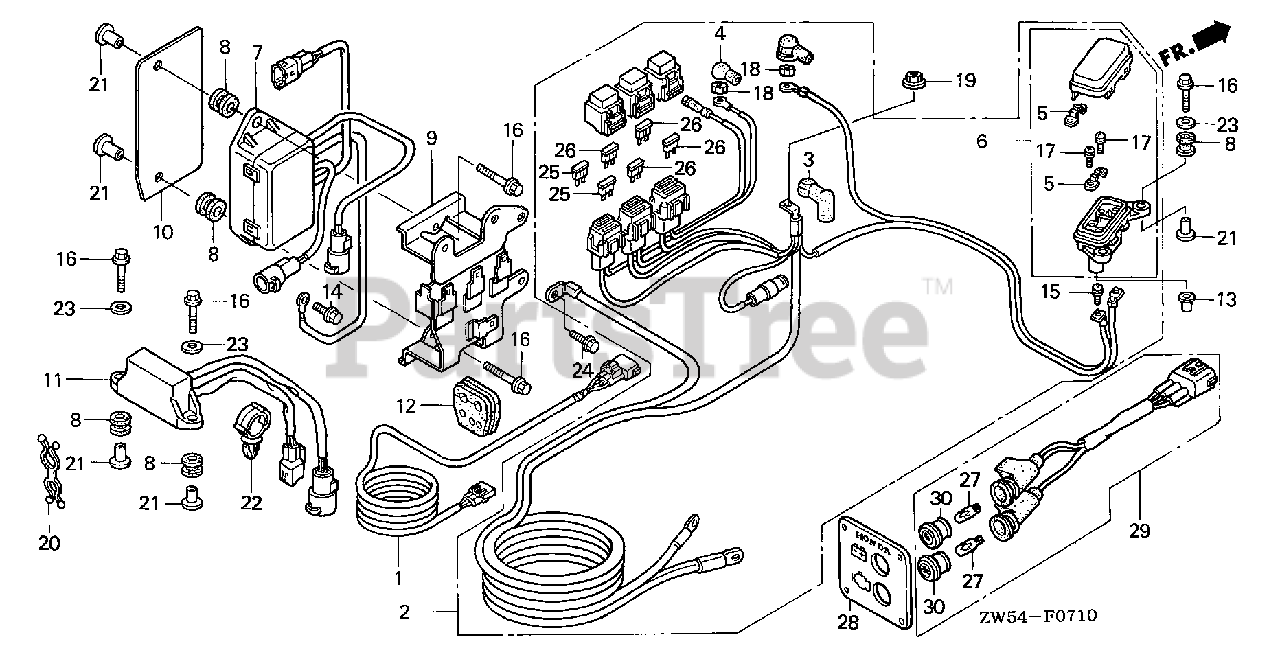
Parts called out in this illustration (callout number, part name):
1	WIRE ASSY., INDICATOR
2	CABLE ASSY., STARTER
3	COVER, STARTER TERMINAL
4	COVER A, MAGNETIC SWITCH
5	FUSE (90A)
6	BOX ASSY., FUSE (90A)
7	RELAY ASSY., POWER TILT
8	GROMMET, RELAY
9	BRACKET, RELAY
10	INSULATOR, RELAY
11	RELAY ASSY., MAIN
12	GROMMET, CASE (LOWER) (A)
13	GROMMET A, LEG SHIELD
14	BOLT, FLANGE (6X12)
15	BOLT-WASHER (5X9)
16	BOLT, FLANGE (6X25)
17	SCREW-WASHER (5X10)
18	NUT, HEX. (6MM)
19	NUT-WASHER (8MM)
20	CLIP, PURSE LOCK
21	COLLAR, MODULE IGNITION CONTROL CASE (CDI)
22	CLIP, WIRE HARNESS (BLACK)
23	WASHER, PLAIN (6MM)
24	BOLT, FLANGE (8X18)
25	FUSE, BLADE (10A)
26	FUSE, BLADE (30A)
27	BULB, WEDGE BASE (T6.5) (12V 3W)
28	PANEL, INDICATOR (2-BULB)
29	LAMP ASSY., INDICATION (2-BULB)
30	LENS, SPEEDOMETER PILOT
31	TIE, CABLE (NATURAL 2.4X92)
